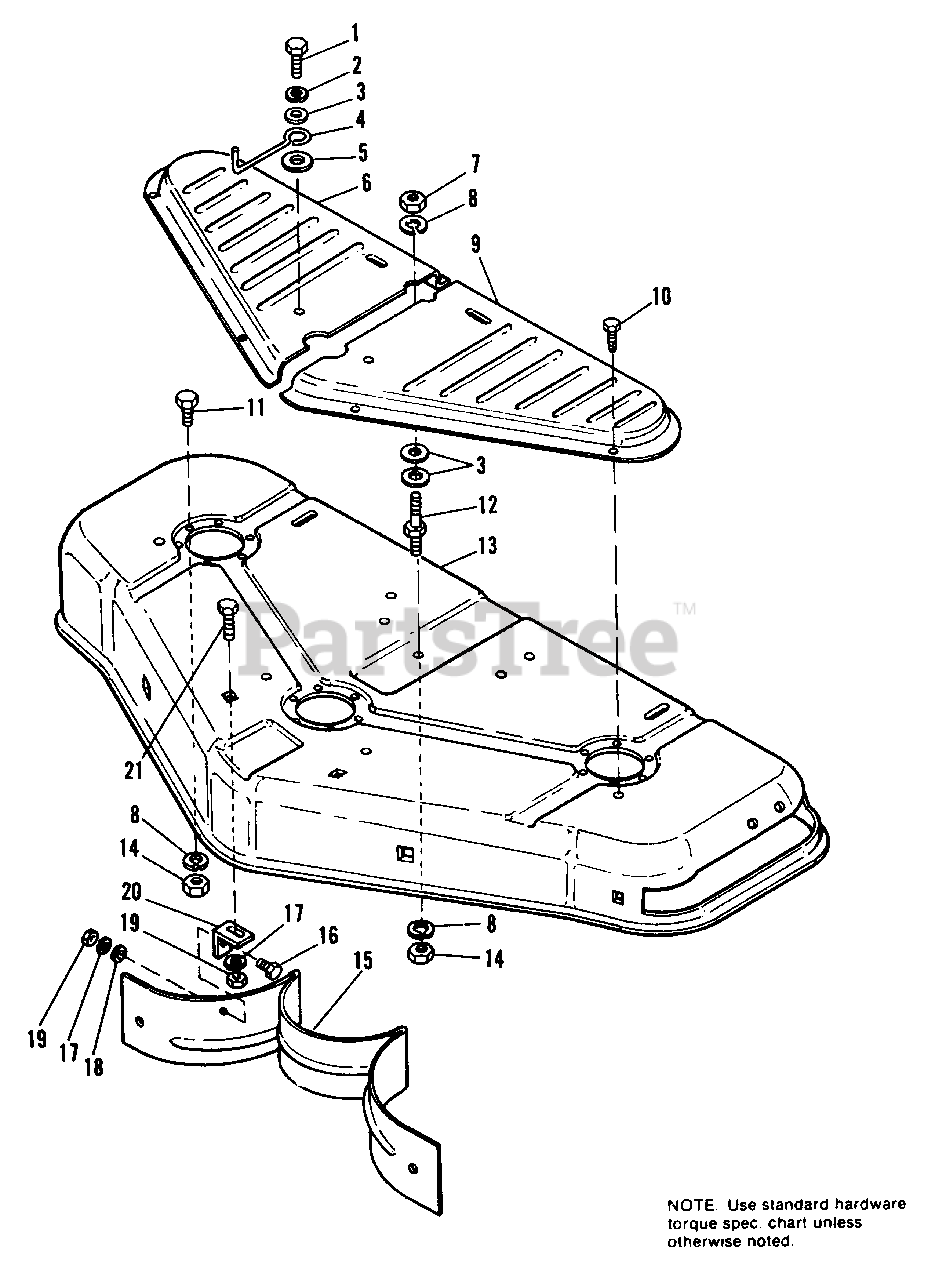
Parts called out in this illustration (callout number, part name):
1	CAPSCREW, Hex Hd., 5/16-18 x 3/4
2	LOCKWASHER, 5/16
3	WASHER, Plain, 5/16
5	WASHER, Plain, 1/2
6	COVER, Half, L.H.
7	LOCKNUT, Hex, 3/8-16
8	LOCKWASHER, 3/8
9	COVER, Half, R.H.
10	SCREW, Hex, Self Tapping, 1/4-20 x 3/8
11	CAPSCREW, Hex Hd, 3/8-16 x 3/4
13	HOUSING, 36"
14	NUT, Hex, Full, 3/8-16
15	BAFFLE, Mower
16	CAPSCREW, Hex Hd., 1/4-20 x 5/8
17	LOCKWASHER, 1/4
18	WASHER, Plain, 1/4
19	NUT, Hex, Full, 1/4-20
20	CLIP, Baffle
21	SCREW, Self Tapping, Hex Hd., 1/4-20 x 7/8
